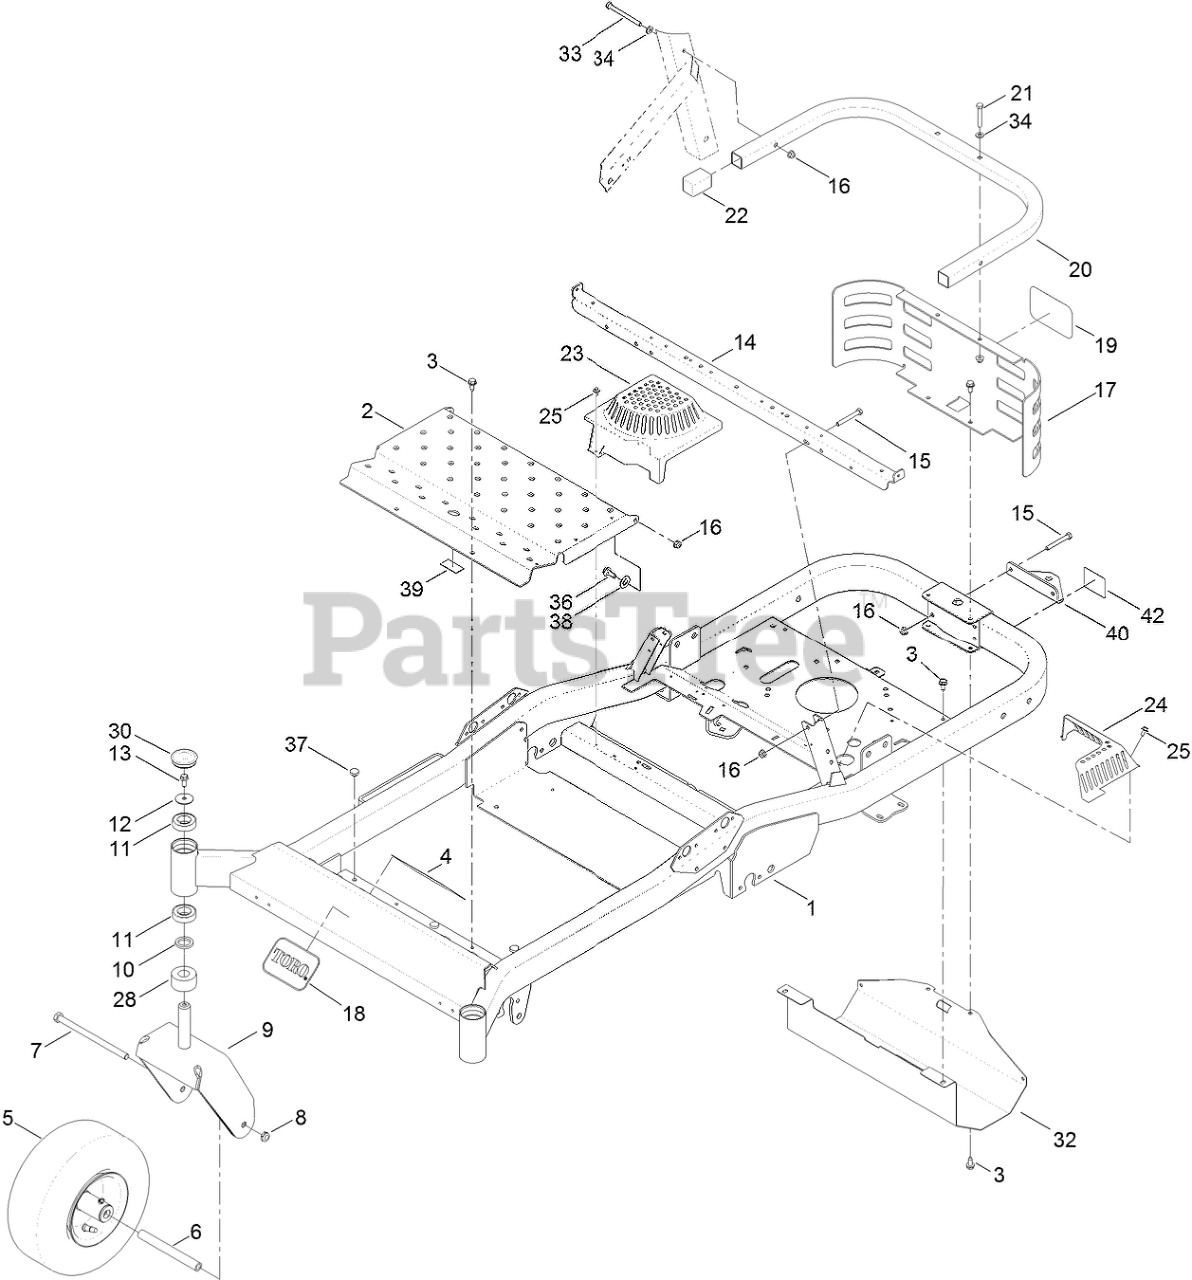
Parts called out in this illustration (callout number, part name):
1	FRAME
2	PAN-FLOOR
3	SCREW-HWHTF
4	DECAL-DANGER
5	TIRE AND WHEEL ASM
6	SPANNER
7	SCREW-HH
8	NUT-LOCK, NI
9	FORK-CASTER
10	WASHER-THRUST
11	BEARING-BALL
12	WASHER-FLAT
13	SCREW-HHF
14	SUPPORT-SEAT
15	SCREW-HH
16	NUT-HF, NI
17	GUARD-REAR
18	DECAL
20	TUBE-GUARD
21	SCREW-HH
23	COVER-FAN, RH
24	COVER-FAN, LH
25	SCREW-HHFTF
28	SPACER-CASTER
30	CAP-GREASE
32	GUARD-MUFFLER
33	SCREW-HH
34	WASHER-PLAIN
36	SCREW-SHOULDER
37	BUMPER
38	WASHER-TEFLON
39	PAD-RUBBER
40	BRACKET-HITCH
